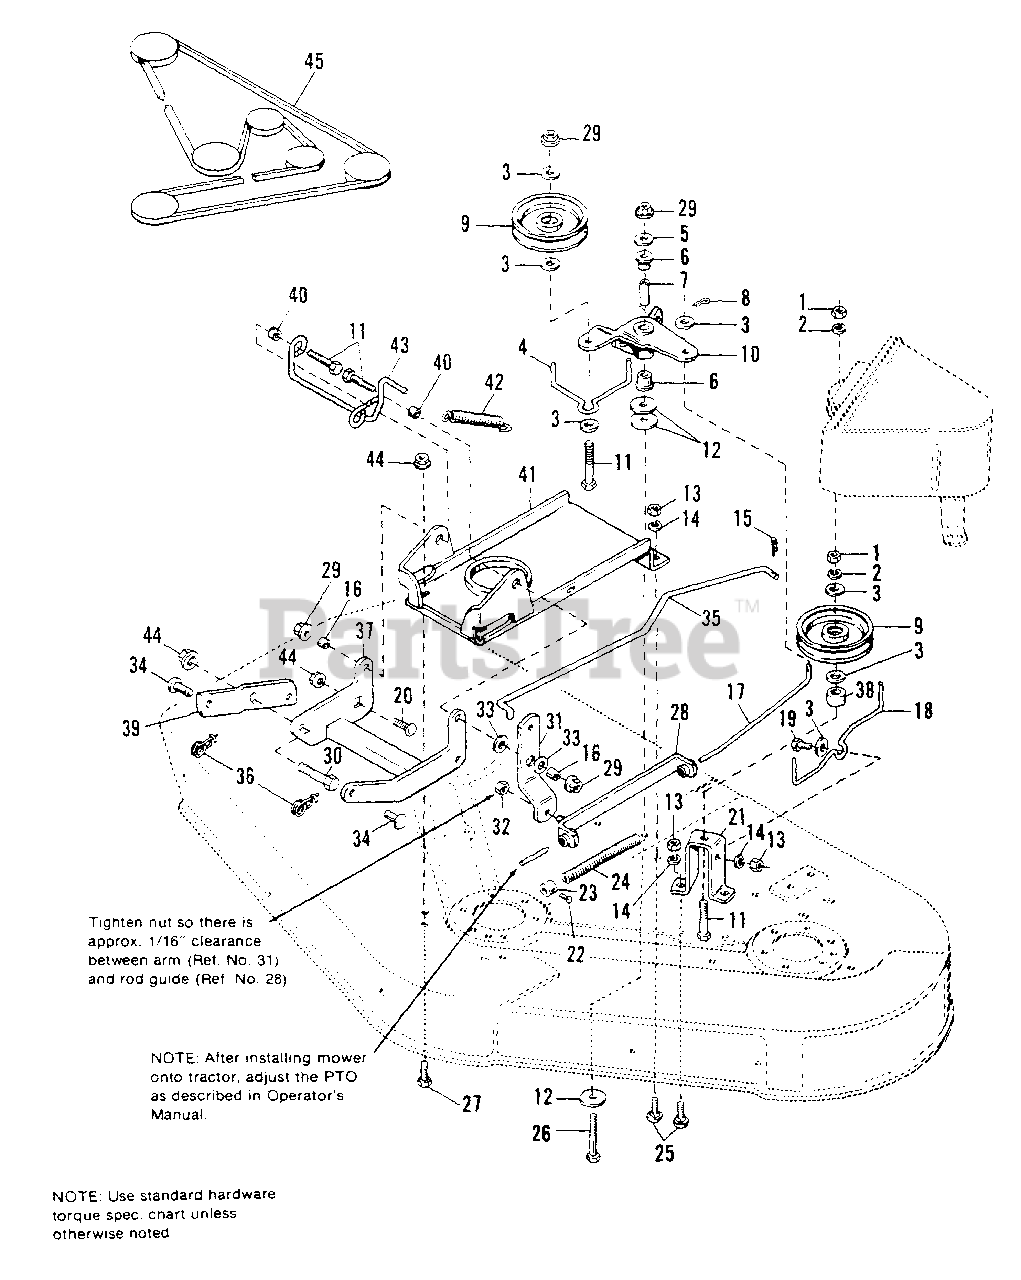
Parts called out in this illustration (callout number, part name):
1	NUT Hex, 3/8-16
2	LOCKWASHER, 3/8
3	WASHER, Plain
5	WASHER Plain 3/8
8	PIN, Cotter, 3/32 x 3/4
9	PULLEY, Idler
10	LEVER ASSY., Clutch
11	CAPSCREW, 3/8-16 x 1-3/4
12	WASHER, Special
13	NUT, Hex, 5/16-18
14	LOCKWASHER, 5/16
15	PIN, Quick, 1-7/8
17	ROD Clutch Mower
19	CAPSCREW, Hex, 5/16-18 x 1
20	CARRIAGE BOLT, 7/16-14 x 1-1/4
21	SUPPORT, Idler
22	SETSCREW, Sq. Hd., 1/4-20 x 3/8
23	COLLAR, Set
25	BOLT, Carriage, 5/16-18 x 3/4
26	CAPSCREW, 3/8-16 x 2-3/4
27	BOLT, Whiziock, 7/16-14 UNC x 1"
28	GUIDE ASSY., Rod
29	NUT, Hex, Flange, 3/8-16
30	CAPSCREW, Hex Hd., 7/16-14 x 1-1/4
31	ARM, Pivot
32	NUT, Jam Ctr. Lock, 5/16-18
33	WASHER, Plain 5/8
35	ROD, Clutch, Tractor P.T.O.
36	PIN, Safety
37	ARM ASSY., Rocker
39	ARM, Rocker
41	SUPPORT ASSY.
42	SPRING, Tension
43	ROD, Brake (42")
43	ROD, Brake (48")
44	NUT, Flange, Whizlock, 7/16-14
45	V-BELT, Mower Drive (42")
45	V-BELT, Mower Drive, Kevlar (48")
